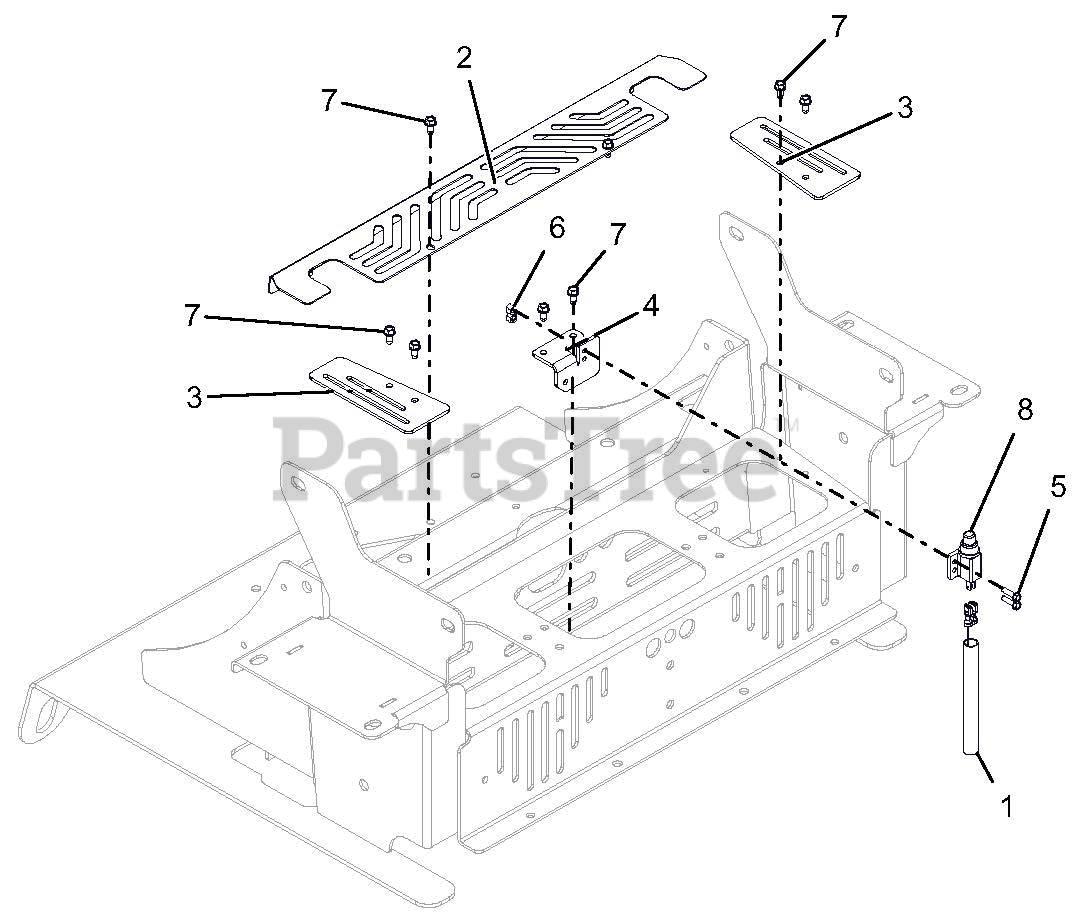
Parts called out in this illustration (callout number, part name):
1	HARNESS, SEAT PLATE SWITCH
2	GUARD, CE REAR ACCESS
3	GUARD, SEAT PLATE FINGER
4	BRKT, SEAT SWITCH MOUNT 272-CE
5	@SCR-MCH 10-24X.75 HWH YWZC
6	NUT-LK-NYL #10-24 YWZC
7	SCR-TAP .25-20X.50 HWH TR YWZ
8	SWITCH (N.0.) RUBBER SEALED
